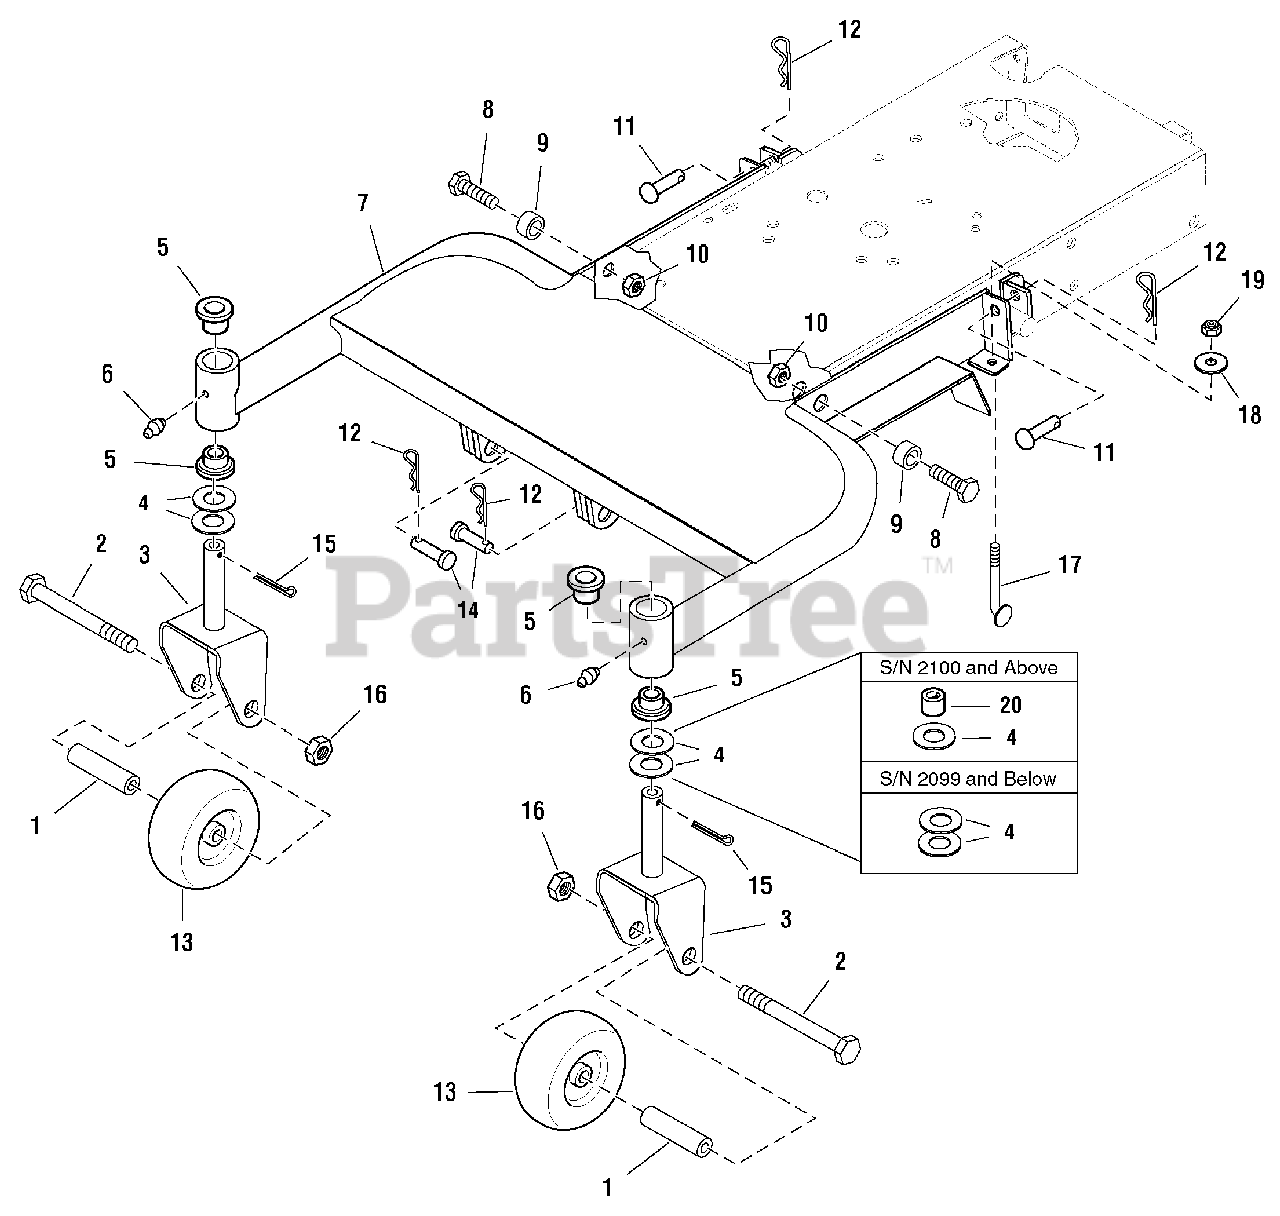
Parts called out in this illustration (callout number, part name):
2	CAPSCREW, Hex Head, 1/2-13 x 4-1/2, Black
3	BRACKET & SHAFT ASSEMBLY
4	WASHER, 3/4, Black
6	FITTING, Lube
7	FRAME ASSEMBLY
8	CAPSCREW, Hex Head, 3/8-16 x 1-1/4, Black
10	NUT, Hex Flange Lock, 3/8-16, Black
11	PIN, Round Head, Drilled, 3/8 x 2, Black
12	CLIP, Hair Pin, Black
13	WHEEL, Caster
14	PIN, Clevis, Black
15	PIN, Cotter, 1/4 x 2, Black
16	NUT, Hex Lock Light, 1/2-13, Black
17	ROD, Height Adjuster
19	NUT, Hex Lock, 5/16-18
20	SPACER
